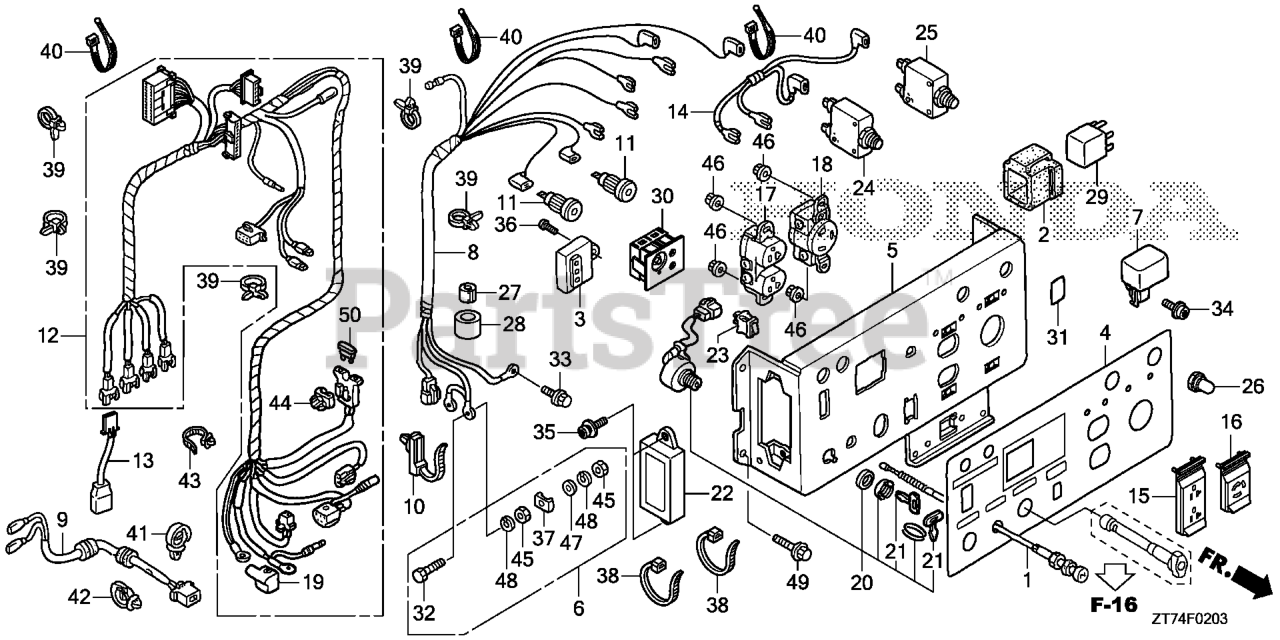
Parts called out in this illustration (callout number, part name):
1	CABLE, CHOKE
2	CUSHION, IGNITION CONTROL MODULE (CDI) (NOT AVAILABLE)
3	IGNITION UNIT
4	MARK, CONTROL PANEL (AG)
5	PANEL, CONTROL (AG)
6	TERMINAL SET, GROUND
7	RECTIFIER, REGULATOR (NOT AVAILABLE)
8	WIRE HARNESS ASSY., MAIN (AG)
9	WIRE HARNESS ASSY., ENGINE
10	BAND, HARNESS OFFSET (30) (145MM) (DARK GRAY)
11	SOCKET, COMPOSITE
12	WIRE HARNESS ASSY., CONTROL (AG)
13	SUB-WIRE HARNESS ASSY., CONTROL (AG)
14	SUB-WIRE ASSY.
15	COVER, RECEPTACLE (20A-125V)
16	COVER, RECEPTACLE (30A-125V)
17	RECEPTACLE (20A/125V)
18	RECEPTACLE (3-PRONG) (30A/125V)
19	COVER, BATTERY TERMINAL (NOT AVAILABLE)
20	SWITCH ASSY., COMBINATION
21	KEY
22	SENSING UNIT (CO)
23	SWITCH, AUTO-THROTTLE (OTAX)
24	PROTECTOR, CIRCUIT (20A)
25	PROTECTOR, CIRCUIT (30A)
26	COVER, CIRCUIT PROTECTOR
27	FILTER, SUB NOISE (AC)
28	SUPPORTER, FILTER
29	RELAY ASSY., POWER (5P)
30	LED ASSY., INDICATER
31	MARK, FUSE
32	BOLT, HEX. (6X28)
33	BOLT, FLANGE (6X12) (CT200)
34	BOLT, FLANGE TORX (6X10)
35	BOLT-WASHER (5X15) (TORX)
36	SCREW, PAN (5X13)
37	RETAINER (6MM)
38	BAND, WIRE (95MM)
39	TIE, CABLE (NATURAL 225X5.0)
40	TIE, CABLE (NATURAL 154X3.4)
41	CLIP, WIRE HARNESS (25MM)
42	CLIP, HARNESS
43	CLIP, HARNESS BAND (145MM) (BLACK)
44	CLIP, CONNECTOR HOLDER (BROWN)
45	NUT, HEX. (6MM)
46	NUT, FLANGE (4MM)
47	WASHER, PLAIN (6MM)
48	WASHER, SPRING (6MM)
49	BOLT, FLANGE (6X10)
50	FUSE, BLADE (5A)
